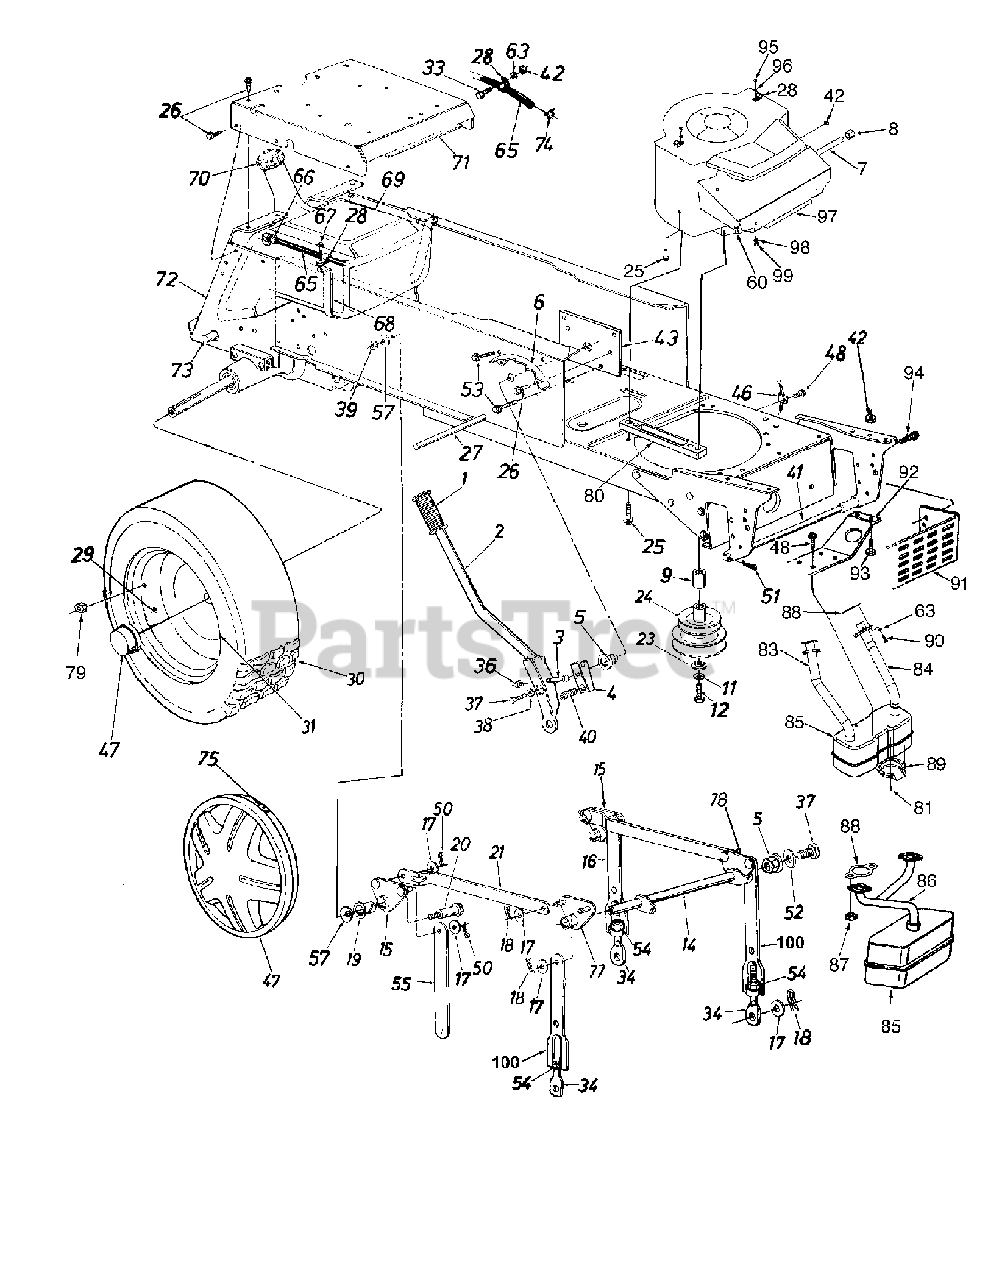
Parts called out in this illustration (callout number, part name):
1	Grip
4	Lift Shaft Drive
5	Plastic Hex Brg. 5/8" I.D.
8	Pipe Cap 3/8-18 Npt.
9	Spacer
11	L-Washer 7/16" I.D.
12	Hex Scr. 7/16-20 x 2"
14	Lift Shaft Assembly
15	Lift Pivot Brkt. Assembly
16	Deck Lift Link: Rear
17	Flat Washer
18	Hairpin Cotter
19	Nyliner 5/8" I.D. x .88"
20	Shld. Bolt
24	Engine Pulley
25	Hx Wsh Hd. Scr. 3/8-16 x 1.25"
26	Hx Roll Scr. 5/16-18 x .75"
27	Running Board Rod
28	Clamp
29	Air Valve
30	Rear Wheel Assembly Comp.
31	Rear Wheel Rim Only
33	Hex Bolt 1/4-20 x .62"
34	Eye Bolt Adj. Link 1/2-13 Thd.
36	Hex Cent. L-Nut 5/16-18 Thd.
37	Hex Bolt 5/16-24 x .62"
38	L-Washer 5/16" I.D.
39	Hex Top L-Nut 3/8-16 Thd.
40	Compression Spring
41	Deck Connecting Rod
42	Hex Sems Nut 1/4-20 Thd.
47	Hub Cap
48	TT-Tap Scr. 1/4-20 x .5"
50	Cotter Pin .09 Dia. x 1.0"
51	Int. Cotter Pin
52	Flat Washer
53	AB-Tap Scr 5/16-24 x .5"
54	Hex Nut 1/2-13 Thd.
57	Bell Washer .4" I.D. x 1.13" O.D.
60	Hex Bolt 5/16-18 x .75"
63	L-Washer 1/4" I.D.
65	Fuel Line 46"
66	Hose Clamp
67	Hex AB-Tap Scr. 1/4 x .62"
68	Fuel Tank Strap
69	Gas Tank
70	Gas Gauge
71	Seat Plate
74	Hose Clamp
75	Spring Clip
77	Pivot Brkt. Assembly RH
78	Pivot Brkt. Assembly LH
79	Lug Nut 7/16-14 Thd.
80	Engine Mounting Spacer
81	F-Tap Scr. #8-32 x .38"
83	Exhaust Tube RH
84	Exhaust Tube LH
85	Muffler
86	Exhaust Pipe
87	Flange Nut M8 x 1.25 Thd.
88	Exhaust Gasket
89	Muffler Deflector
90	Hex Bolt 1/4-20 x .75"
93	Hex Bolt 1/4-20 x .62"
94	Hex TT-Tap Scr. 5/16-18 x .62"
95	Truss Mach. B-Tap Scr. #10 x .5"
96	Flat Washer .188" I.D. x .438" O.D.
99	Hex Nut 5/16-18 Thd.
100	Front Deck-Link Lift Ass'y
